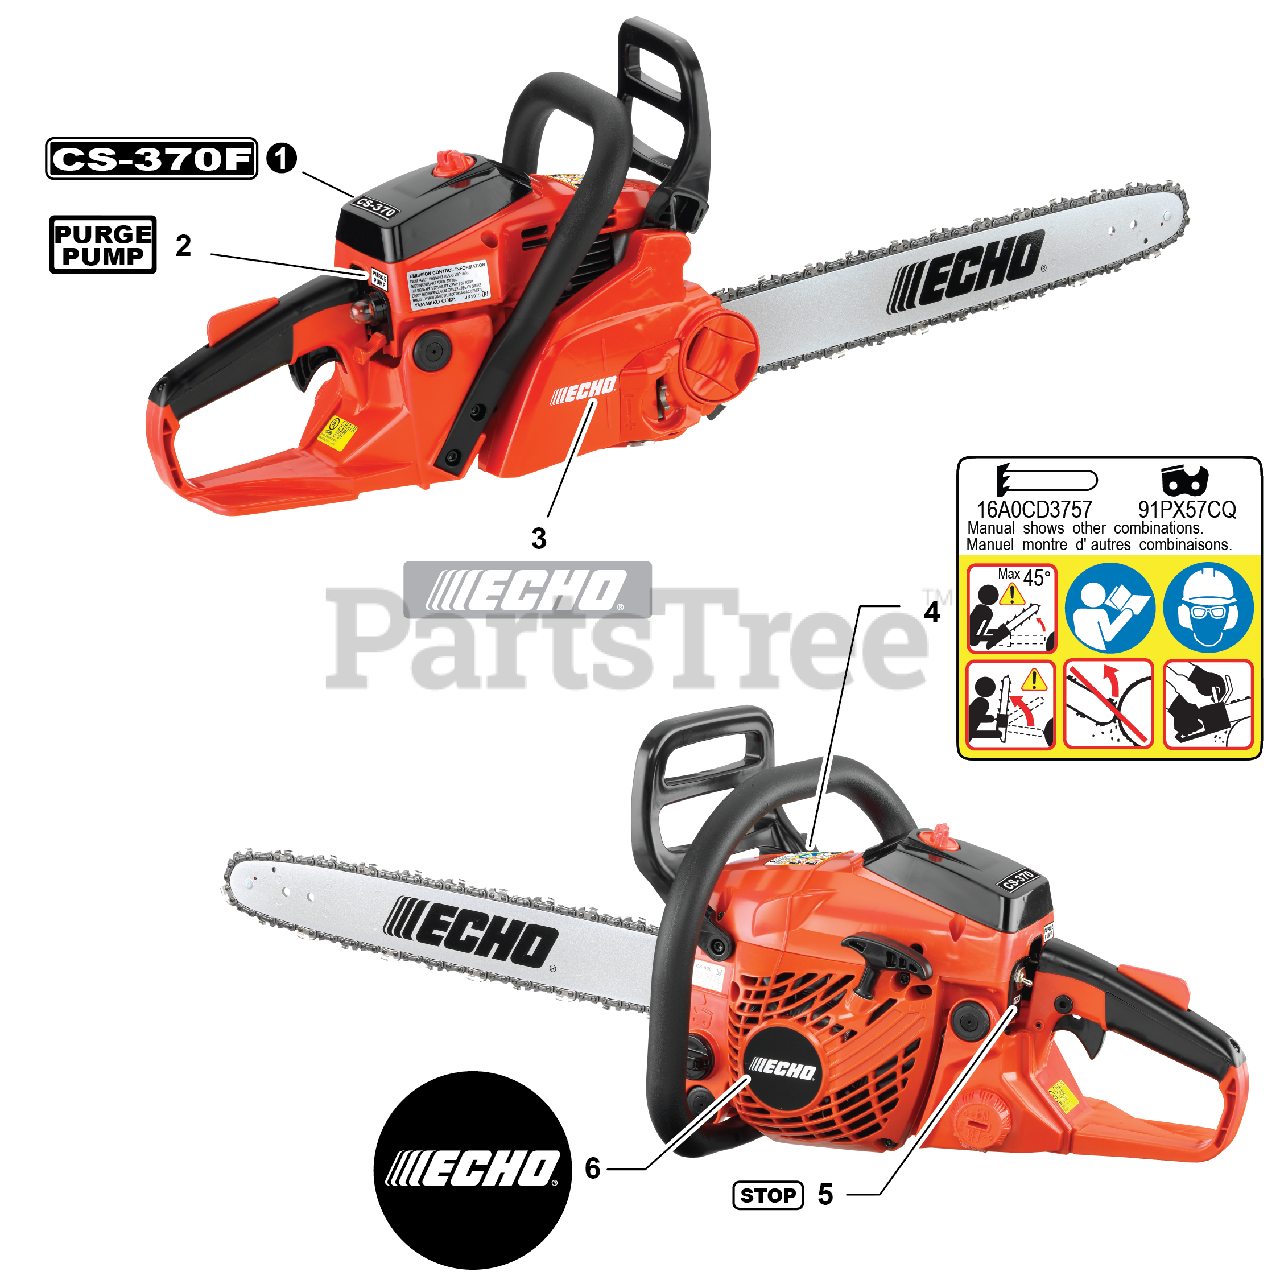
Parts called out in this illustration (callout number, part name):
1	LABEL - MODEL CS-370F
2	LABEL, PURGE PUMP
3	LABEL, ECHO
4	LABEL, CAUTION
5	LABEL, STOP
6	LABEL, ECHO
